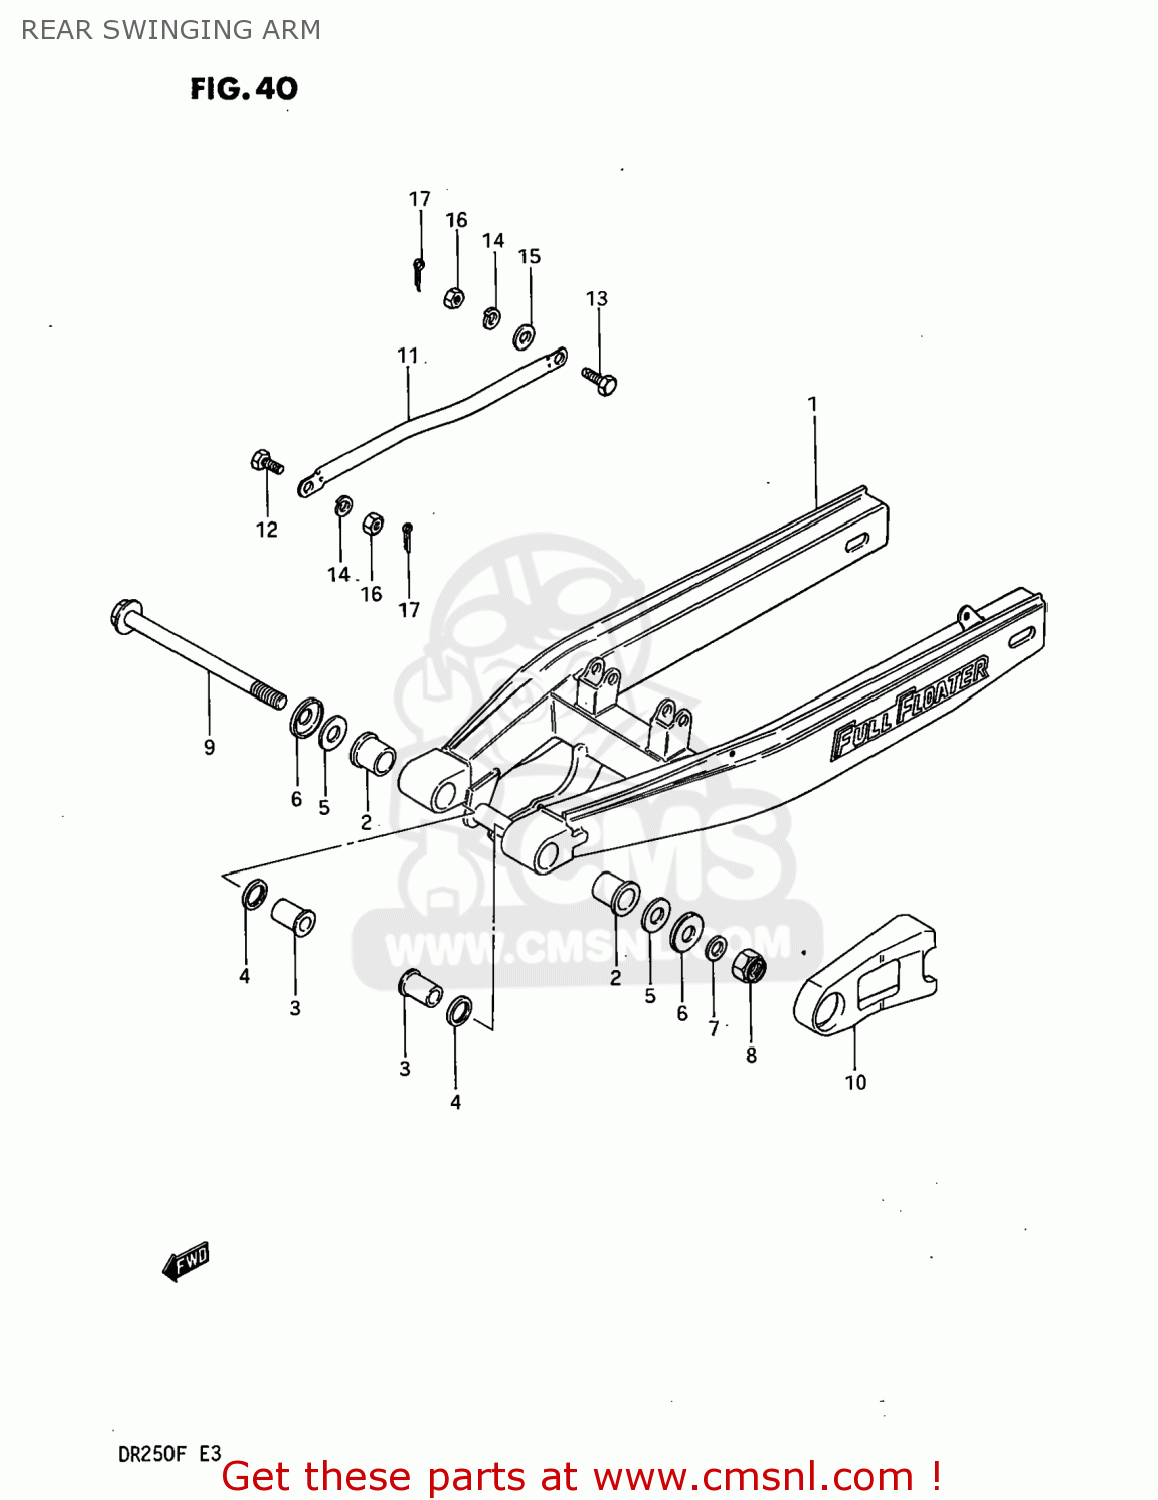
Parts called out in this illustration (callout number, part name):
1	SWING ARM ASSEMBLY,REAR
2	BUSHING,RR SWGARM PIVOT
3	SPACER,RR SWGARM PIVOT OUTER
4	SEAL,OIL(20X27X5)
5	WASHER
6	COVER,REAR SWING ARM DUST
7	WASHER
8	NUT 14MM
9	SHAFT,REAR SWING ARM
10	BUFFER,CHAIN TOUCH DEFLECTOR
11	LINK,REAR TORQUE
12	BOLT
13	BOLT(8X26.5)
14	LOCK WASHER
15	WASHER
16	NUT
17	PIN 20X20
